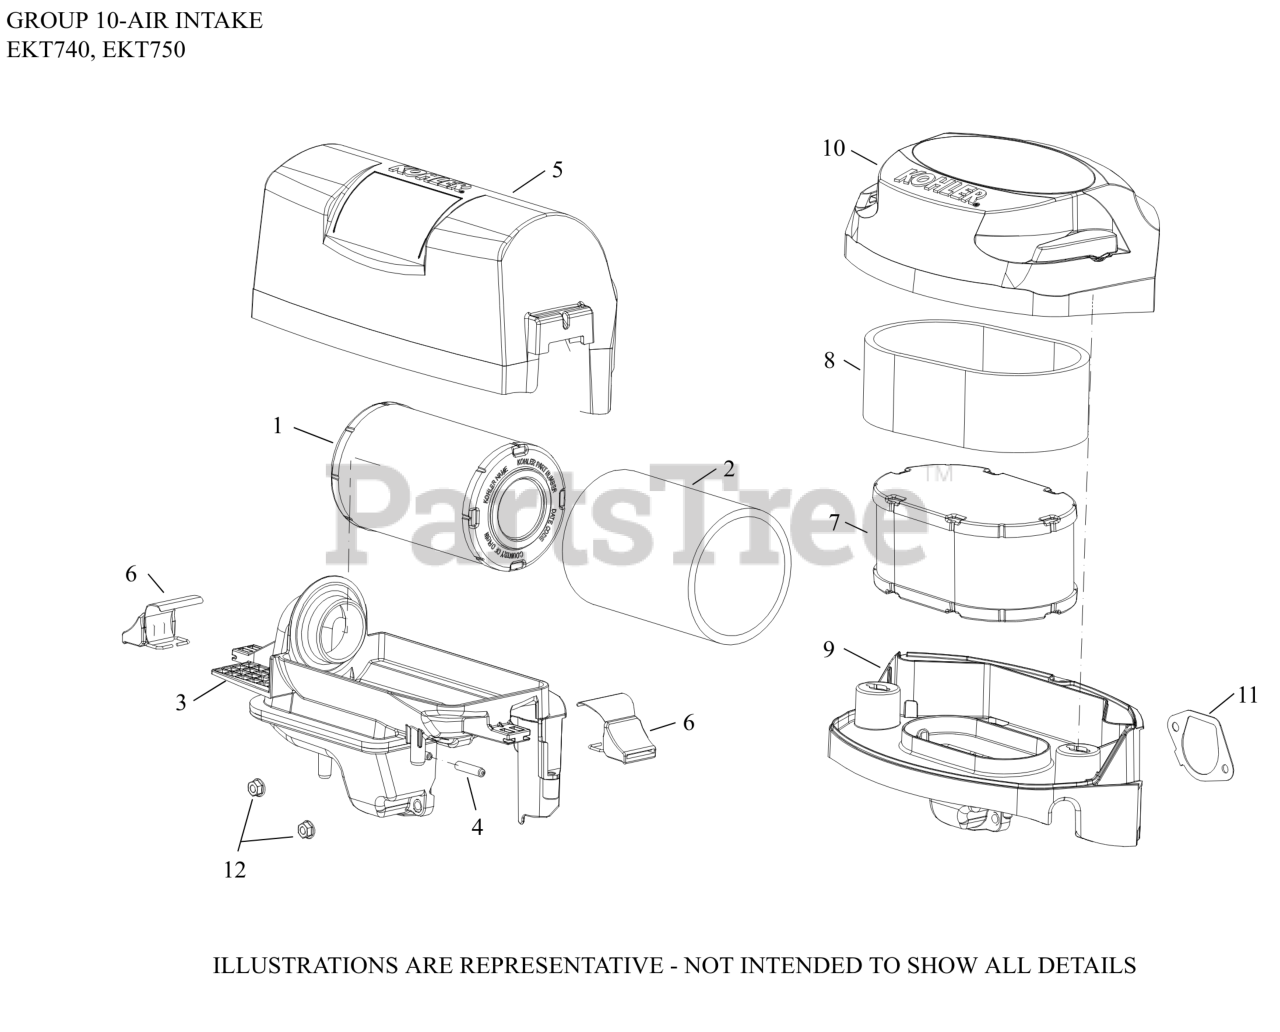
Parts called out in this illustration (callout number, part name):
1	ELEMENT, AIR FILTER
4	CAP, MASKING
5	COVER, AIR CLEANER
6	LATCH ASSY, AIR CLEANER COVER
9	BASE ASSEMBLY, AIR CLEANER
11	GASKET, AIR CLEANER BASE
12	NUT, FLG M6X1.0
